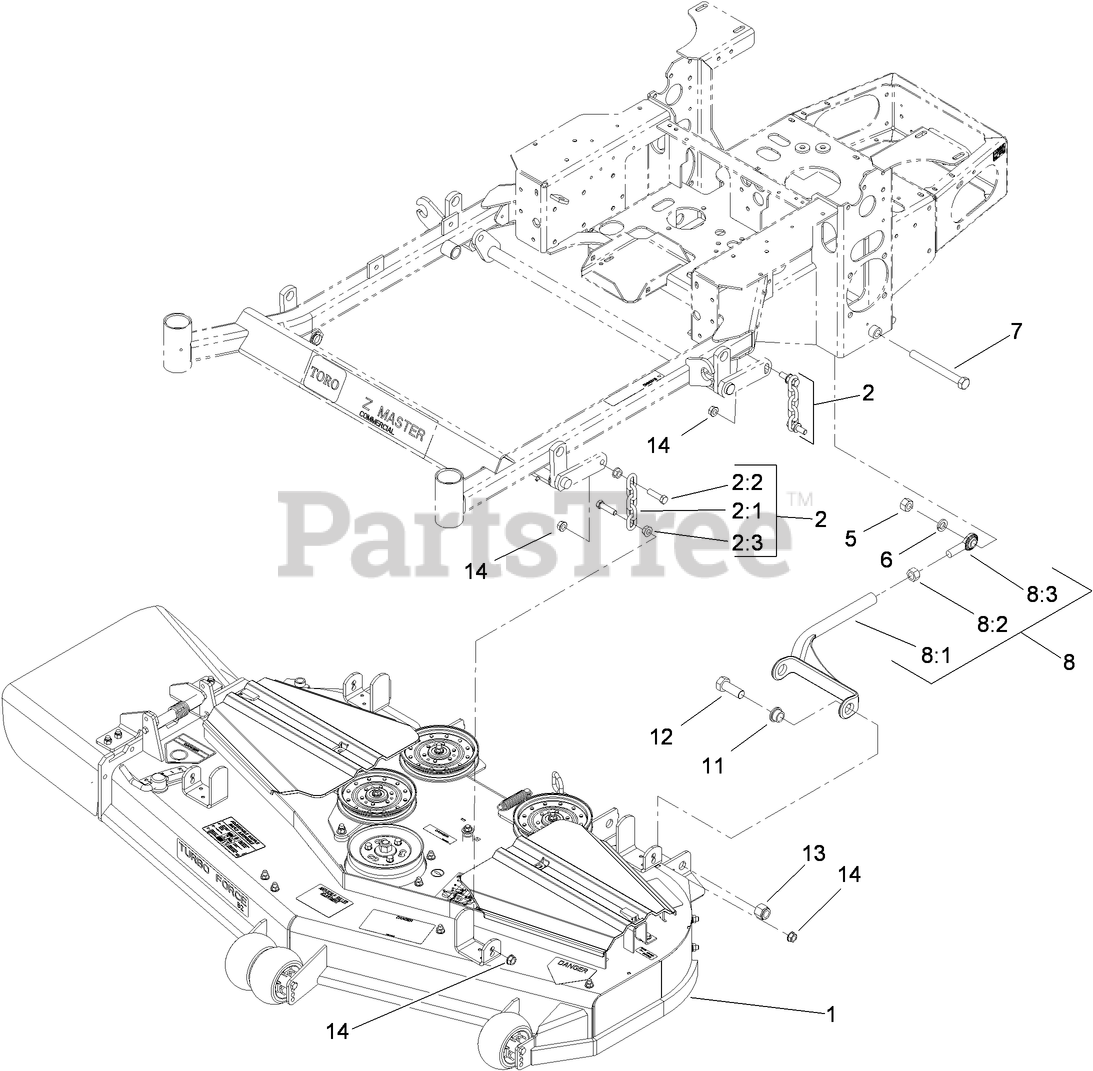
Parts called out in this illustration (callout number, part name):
1	DECK ASM
2	DECK CHAIN ASM
2:1	CHAIN-LIFT, DECK
2:2	SCREW-HH
2:3	NUT-HF
5	NUT-HEX
6	WASHER-LOCK
8	STRUT ASM
8:1	STRUT-DECK
8:2	NUT-HEX
8:3	BALLJOINT-SPHERICAL
11	BUSHING
12	SCREW-HH
13	NUT-LOCK, NI
14	NUT-HF
